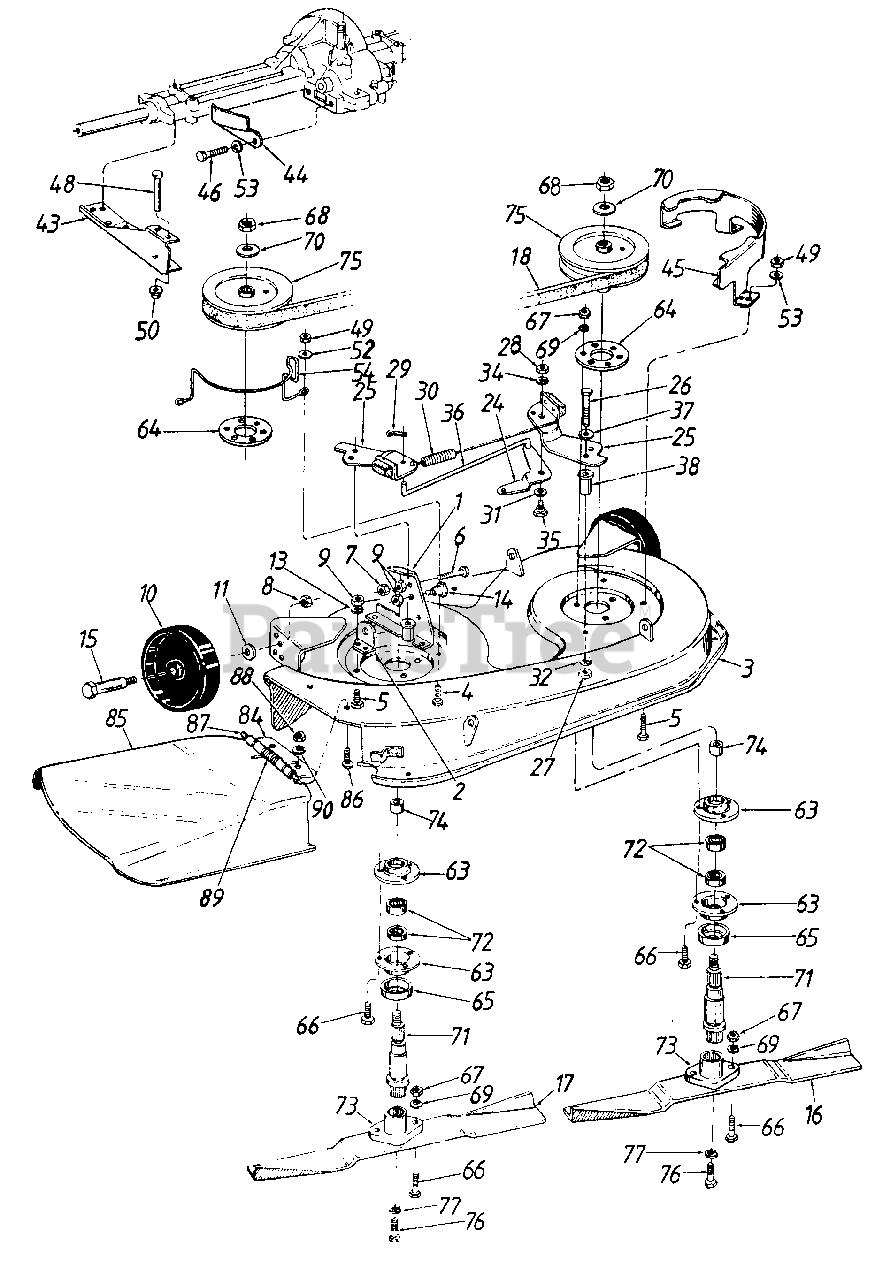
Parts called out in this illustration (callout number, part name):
1	Deck Disengagement Brkt.
2	Rear Deck Brkt. R.H.
3	32" Deck Ass'y.
4	Hex Bolt 1/4-20 x .75" Lg.
5	Hex Bolt 1/4-20 x .62" Lg.
6	Hex Wash. Hd. Scr. 1/4-20 x 1.5" Lg.
7	Hex L-Nut 1/4-20 Thd.
8	Hex L-Nut 3/8-16 Thd.
9	Hex Nut 1/4-20 Thd.
10	Deck Wheel
11	Bell-Wash. .380" I.D. x .88
13	L-Wash. 1/4" I.D.
14	Shld. Bolt .500" Dia. x .215" Lg.
15	Shld. Bolt .498" Dia. x 1.53" Lg.
16	L.H. High-Lift Blade
17	R.H. High-Lift Blade
18	V-Belt
24	Deck Brake Bracket
25	Deck Brake Brkt. Ass'y.
26	Hex Bolt 5/16-24 x 2" Lg.
27	Hex Nut 5/16-24 Thd.
28	Hex Nut 1/4-20 Thd.
29	Cotter Pin 1/16" Dia.
30	Extension Spring
31	Fl-Wash. .406" I.D. x 1.0" O.D.
32	L-Wash. 5/16" I.D.
34	L-Wash. 1/4" I.D.
35	Shld. Bolt .375" Dia. x .181"Lg.
36	Deck Control Rod
37	Shld. Spacer x .27" Lg.
38	Spacer 1.46" Lg.
43	Lower Outside Belt Guard
44	Lower Inside Belt Guard
45	Belt Guard Deck R.H.
46	Hex Bolt 1/4-20 x .62" Lg.
49	Hex Nut 1/4-20 Thd.
50	Speed Nut 1/4" Rod
52	Bell-Wash. .265" I.D. x .75
53	L-Wash. 1/4" I.D.
54	Deck Belt Guard
63	Bearing Housing
64	Reinforcement Plate
65	Bearing Shield
66	Hex Bolt 5/16-24 x 1.0" Lg.
67	Hex Nut 5/16-24 Thd.
68	Hex Jam Nut 5/8-18 Thd.
69	L-Wash. 5/16" I.D.
70	Bell-Wash. 5/8" I.D.
71	Blade Spindle
72	Ball Bearing
73	Blade Adapter
74	Spacer
75	5" Dia. Pulley
76	Hex Bolt 3/8-24 x 1.0" Lg.
77	L-Wash. 3/8" I.D. H.D.
84	Chute Bracket
85	Chute
86	Truss.-Mach. Scr. 1/4-20 x .75" Lg.
87	Hinge Pin
88	Hex Nut 1/4-20 Thd.
89	Torsion Spring 1.14" Lg.
90	L-Wash. 1/4" I.D.
